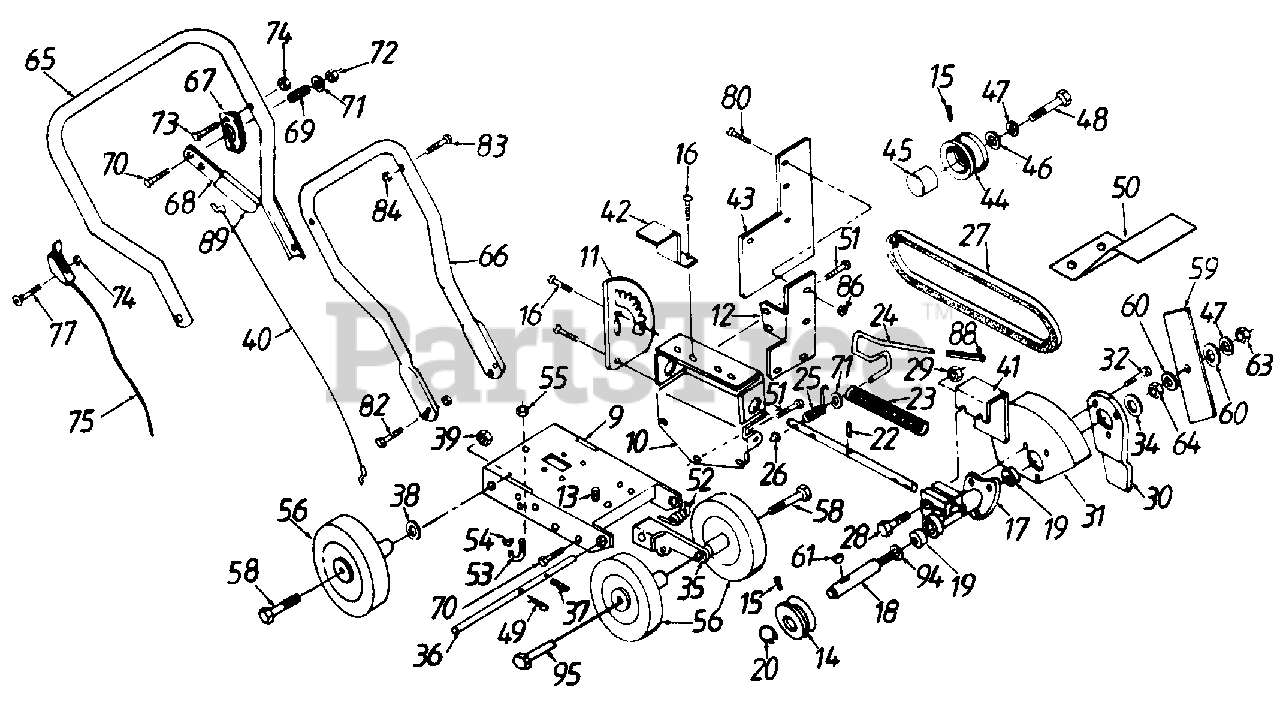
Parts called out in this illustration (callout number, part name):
9	Base Edger Frame
10	Side Plate
11	Index Plate
12	Deflector Bracket
13	Bolt Engine Mtg.
14	Pulley Cutterhead
15	Set Screw
16	Screw #10-32 x 1/2"
17	Casting Cutterhead
18	Shaft-Cutterhead
19	Bushing-Bronze
20	Retaining Ring
22	Roll Pin
23	Spring Cutterhead
24	Index Lever
25	Spring Index Lever
26	Push Nut Retainer 5/16"
27	V-Belt
28	Hex Bolt 5/16-18 x 1l/2"
29	Hex Nut 5/16-18 Thd.
30	Edge Guide
31	Guard-Blade
32	Screw #124 x 3/4"
34	Flat Washer
35	Wheel Arm-Front
36	Wheel Axle-Front
37	Roll Pin
38	Fl-Wash. 3/8 I.D.
39	Hex Flange Nut 3/8-16
40	Cable Depth Control
41	Belt Guardutterhead
42	Belt Guard-Engine
43	Debris Deflector
44	Pulley Half Engine
45	Spacer-Engine Pulley
46	Fl-Wash. 3/8" I.D.
47	L-Wash. 3/8" I.D.
48	Hex Bolt 3/8-24 x 1n Lg.
49	Hairpin Cotter
51	Tapping Screw 1/4-20 x 5/8"
52	Spring Front Wheel
54	Cable Guide Half
55	Hex Keps Nut 1/4-20
56	Wheel 7" Marlex
58	Bolt Wheel Axle
59	9" Replacement Blade
60	Fl-Wash. 3/8" I.D.
61	Woodruff Key
63	Hex Nut 3/8-24 Thd.
64	Hex Jam Nut 3/8-24 Thd.
65	Upper Handle
66	Lower Handle
67	Plate Depth Adjust
68	Handle Depth Adjust
69	Spring Adjust Handle
70	Hex Bolt 5/16-18 x 11/2"
71	Fl-Wash. 5/16" I.D.
72	Hex Flange L-Nut 5/16-18 I.D.
73	Hex Bolt 1/4-20 x 1l/4"
74	Hex Flange L-Nut 1/4-20
75	Throme Control-2 HP B&S
77	Eye Bolt
80	Tap Scr. #10-32 x .5" Lg.
82	Hex Bolt 5/16-18 x 5/8"
83	Hex Bolt 5/16-18 x 1-1/4
84	Hex Sems Nut 5/16-18
86	Hex Sems Nut #10-32
88	Vinyl Grip Round
89	Vinyl Grip Flat
94	Fl-Wash.
95	Bolt Wheel Axle
